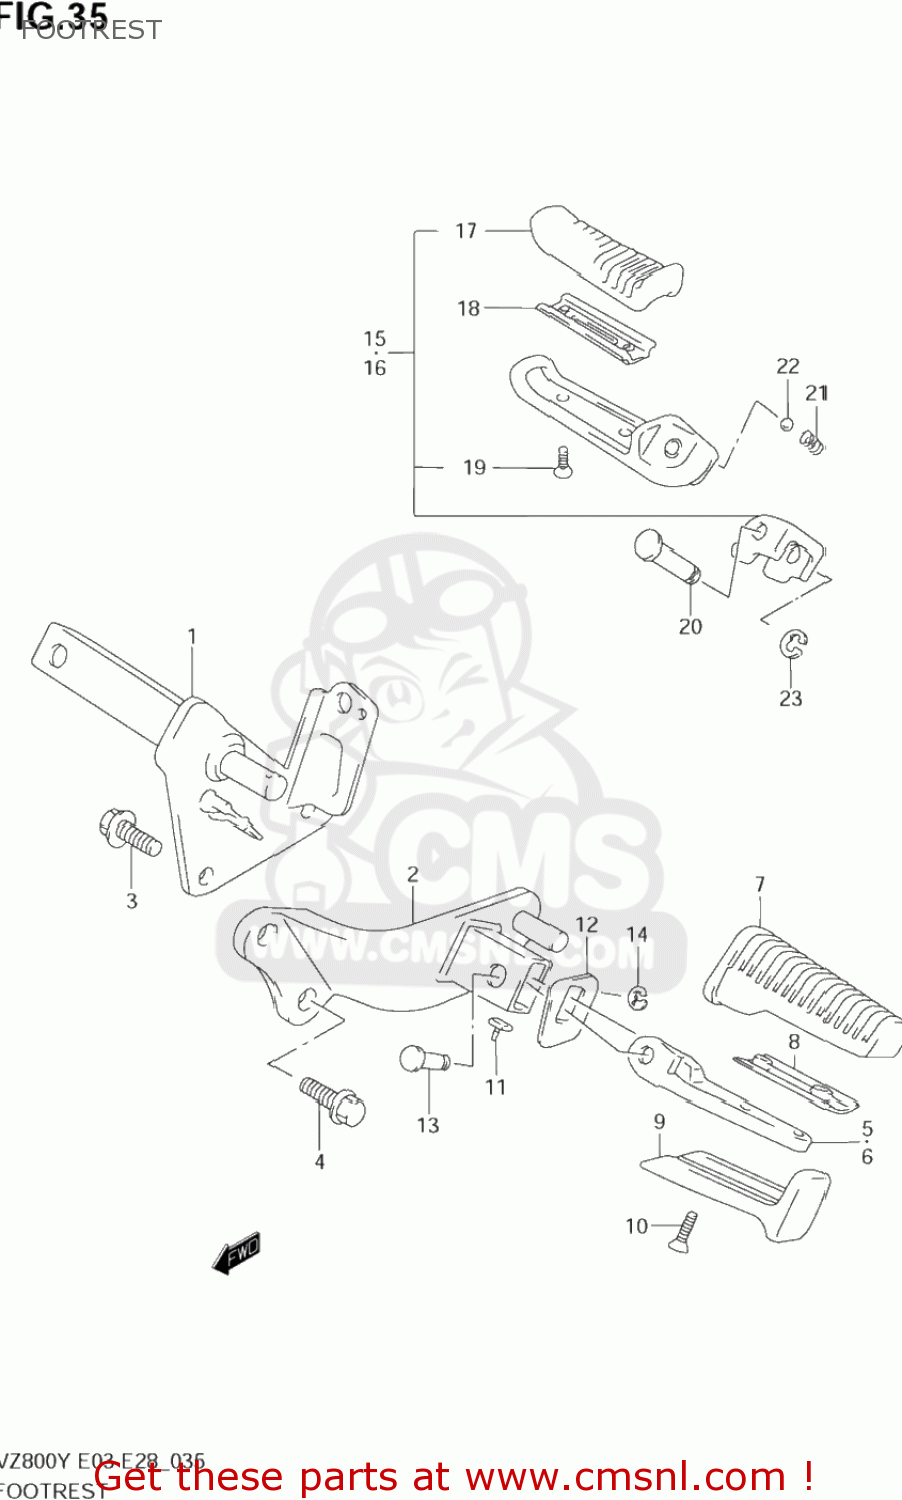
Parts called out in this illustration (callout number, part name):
1	BRACKET,FR FOOTREST,R
2	BRACKET,FR FOOTREST,L
3	BOLT
4	BOLT
5	BAR,FR FOOTREST,R
6	BAR,FR FOOTREST,L
7	RUBBER,FR FOOTREST
8	PLATE,RUBBER STOPPER
9	COVER,FR FOOTREST
10	SCREW(5X20)
11	CUSHION,FR FOOTREST BAR
12	WASHER,FR FOOTREST
13	PIN
14	E.RING
15	FOOTREST ASSY,PILLION,R
16	FOOTREST ASSY,PILLION,L
17	RUBBER,PILLION FOOTREST
18	PLATE,RUBBER STOPPER
19	SCREW(5X16)
20	PIN
21	SPRING
22	BALL
23	E.RING
